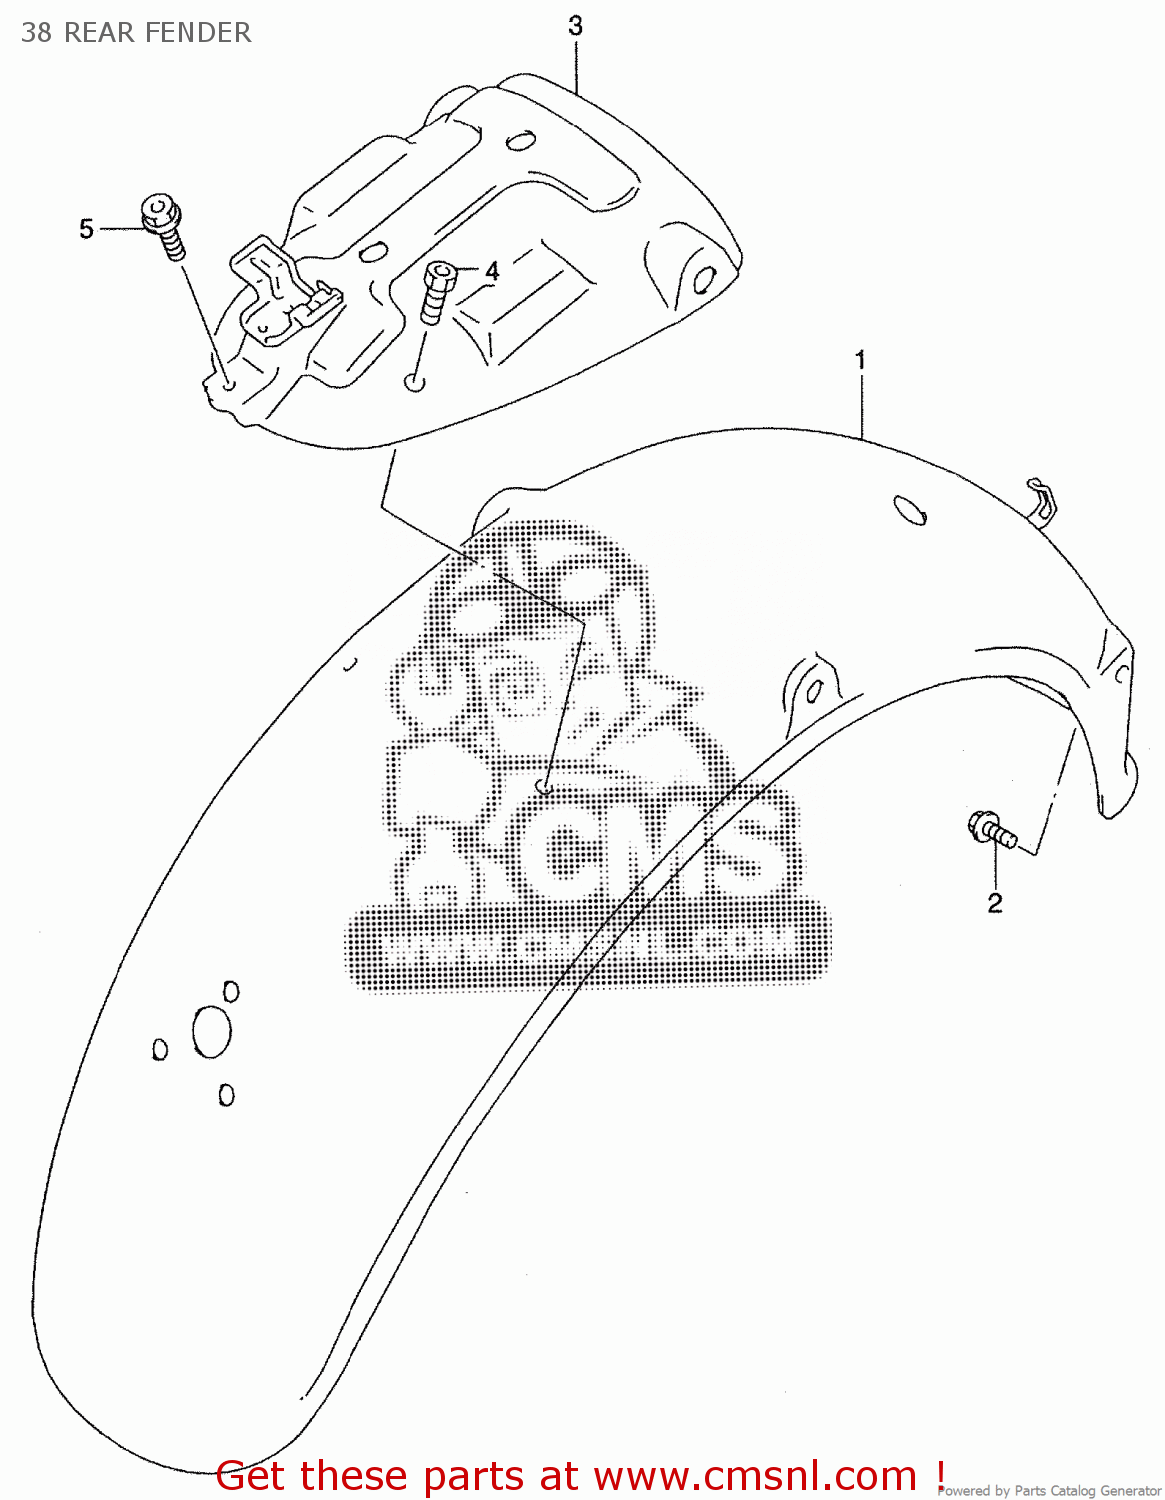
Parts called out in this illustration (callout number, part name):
2	BOLT
4	BOLT 6X16
5	SCREW(8X16)
